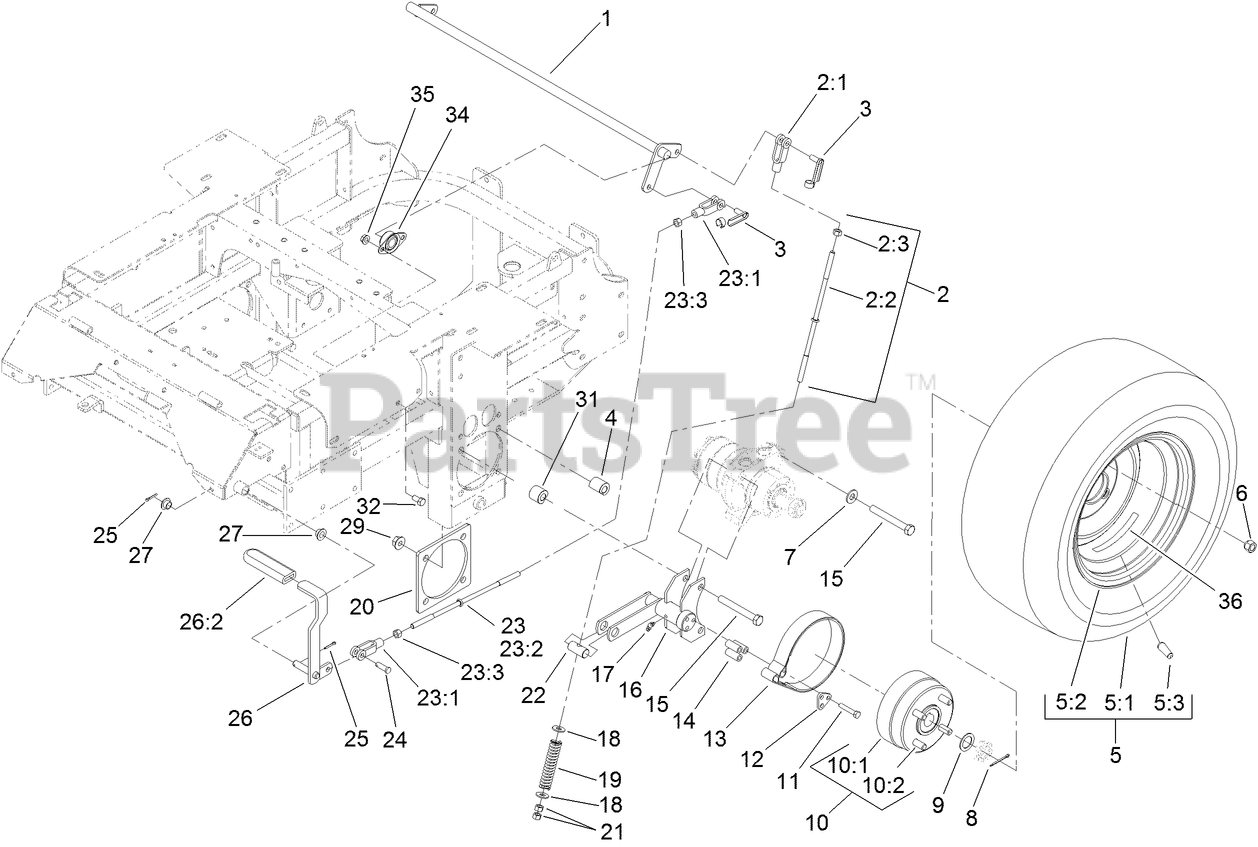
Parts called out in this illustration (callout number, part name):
1	SHAFT-BRAKE
2	BRAKE ROD ASM
2:1	YOKE-LINKAGE, BRAKE
2:2	ROD-BRAKE
2:3	NUT-HEX
3	Pin-Spring, Clevis
4	SPACER-WHEEL, LONG
5	WHEEL AND TIRE ASM
5:1	TIRE
5:3	STEM-VALVE
6	NUT-LUG
7	WASHER-THRUST
8	PIN-COTTER
9	WASHER-SPACER
10	WHEEL HUB ASM
10:1	HUB-WHEEL
10:2	STUD-WHEEL
11	SCREW-HH
12	RETAINER-BAND, BRAKE
13	BAND-BRAKE
14	SPACER
15	SCREW-HH
16	BRACKET-BRAKE
17	FITTING-GREASE
18	WASHER-FLAT
19	SPRING-BRAKE
20	PLATE-REINFORCEMENT
21	NUT-HEX
22	PIN-TRUNION
23	BRAKE ROD ASM
23:1	YOKE-LINKAGE, BRAKE
23:2	ROD-BRAKE
23:3	NUT-HEX
24	PIN-CLEVIS
25	PIN-COTTER
26	BRAKE LEVER ASM
26:2	GRIP-LEVER
27	BEARING-CONTROL
29	NUT-HHF
31	SPACER-WHEEL, SHORT
32	SCREW-HH
34	BEARING-FLANGE, SIDE
35	NUT-HHF, WHIZ
36	DECAL
